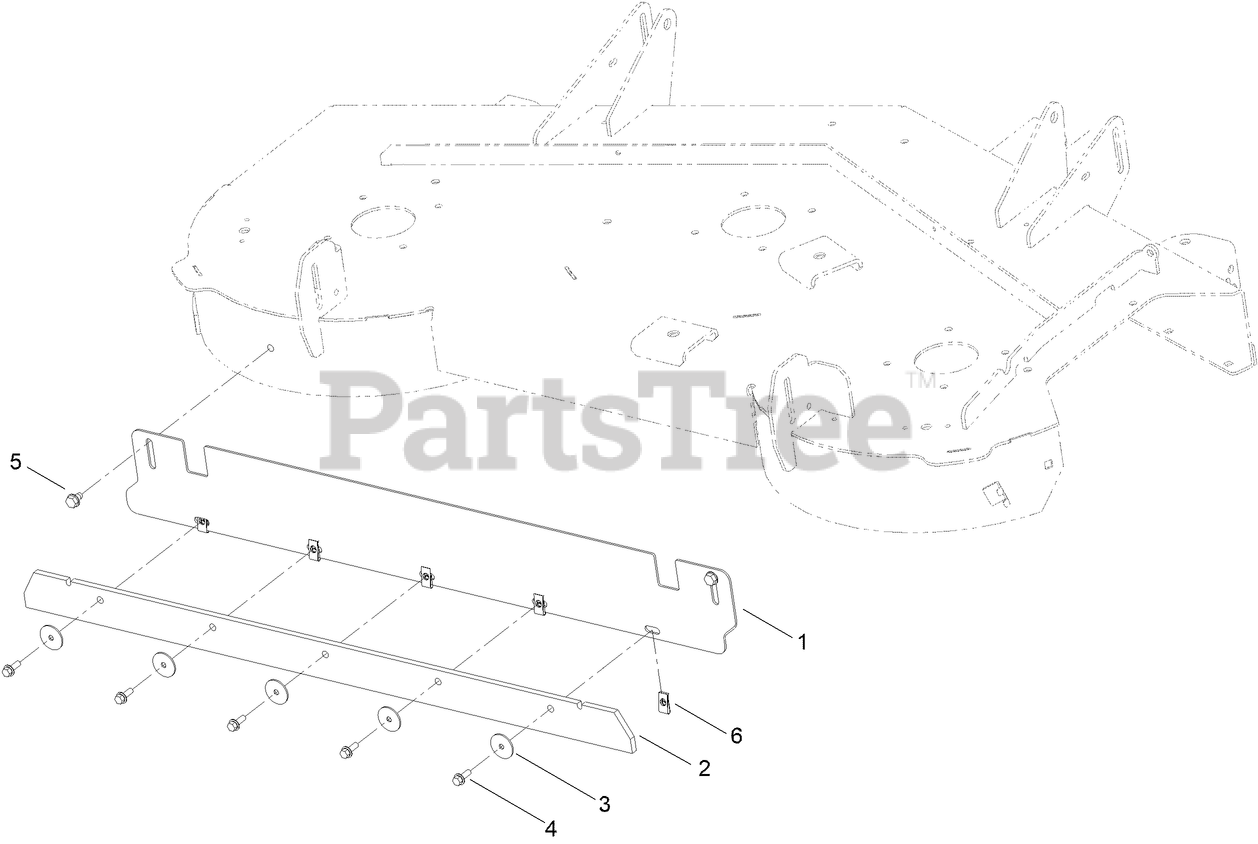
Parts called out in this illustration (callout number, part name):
1	BRACKET-STRIPING, 50"
3	WASHER-FLAT
4	SCREW-HHF
5	SCREW-HWH, THD ROLL
6	NUT-SPEED
